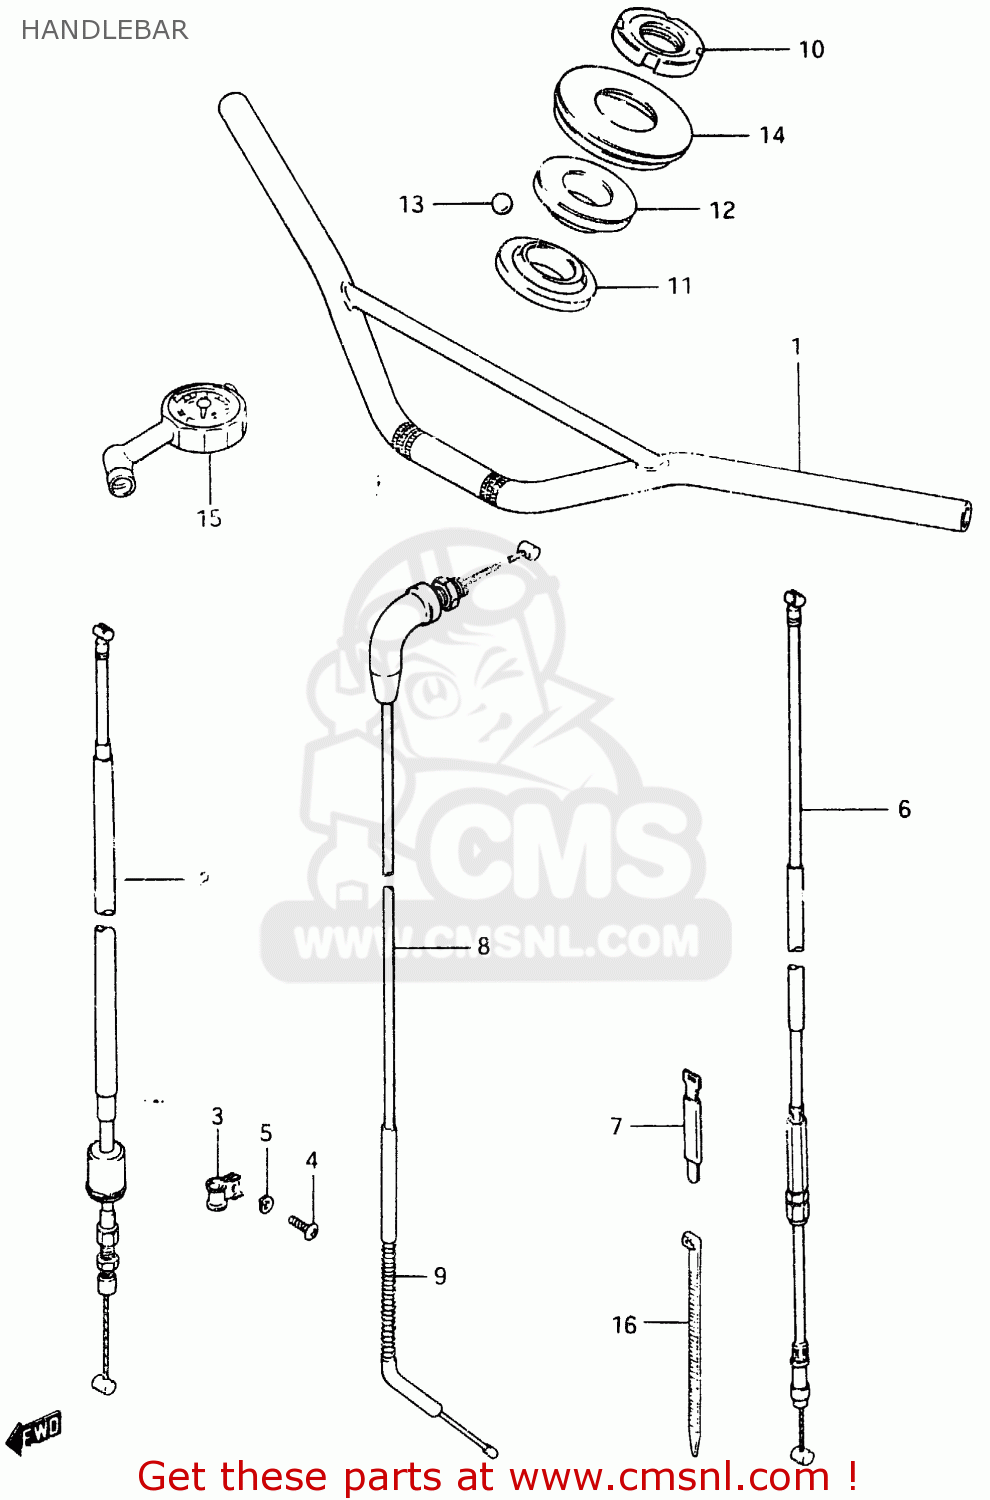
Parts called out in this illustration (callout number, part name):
1	HANDLEBAR
2	CABLE ASSEMBLY,FRONT BRAKE
3	GUIDE,CABLE
4	SCREW
5	LOCK WASHER
6	CABLE ASSEMBLY,CLUTCH
7	CLAMP
8	CABLE ASSEMBLY,THROTTLE
9	PROTECTOR,CABLE
10	NUT,STEERING STEM
11	RACE,STEERING,INNER,UPPER
12	RACE,STEERING,OUTER,UPPER
13	BALL
14	SEAL,STEERING UPR DUST
15	GAUGE ASSY,AIR PRESSURE
16	CLAMP
